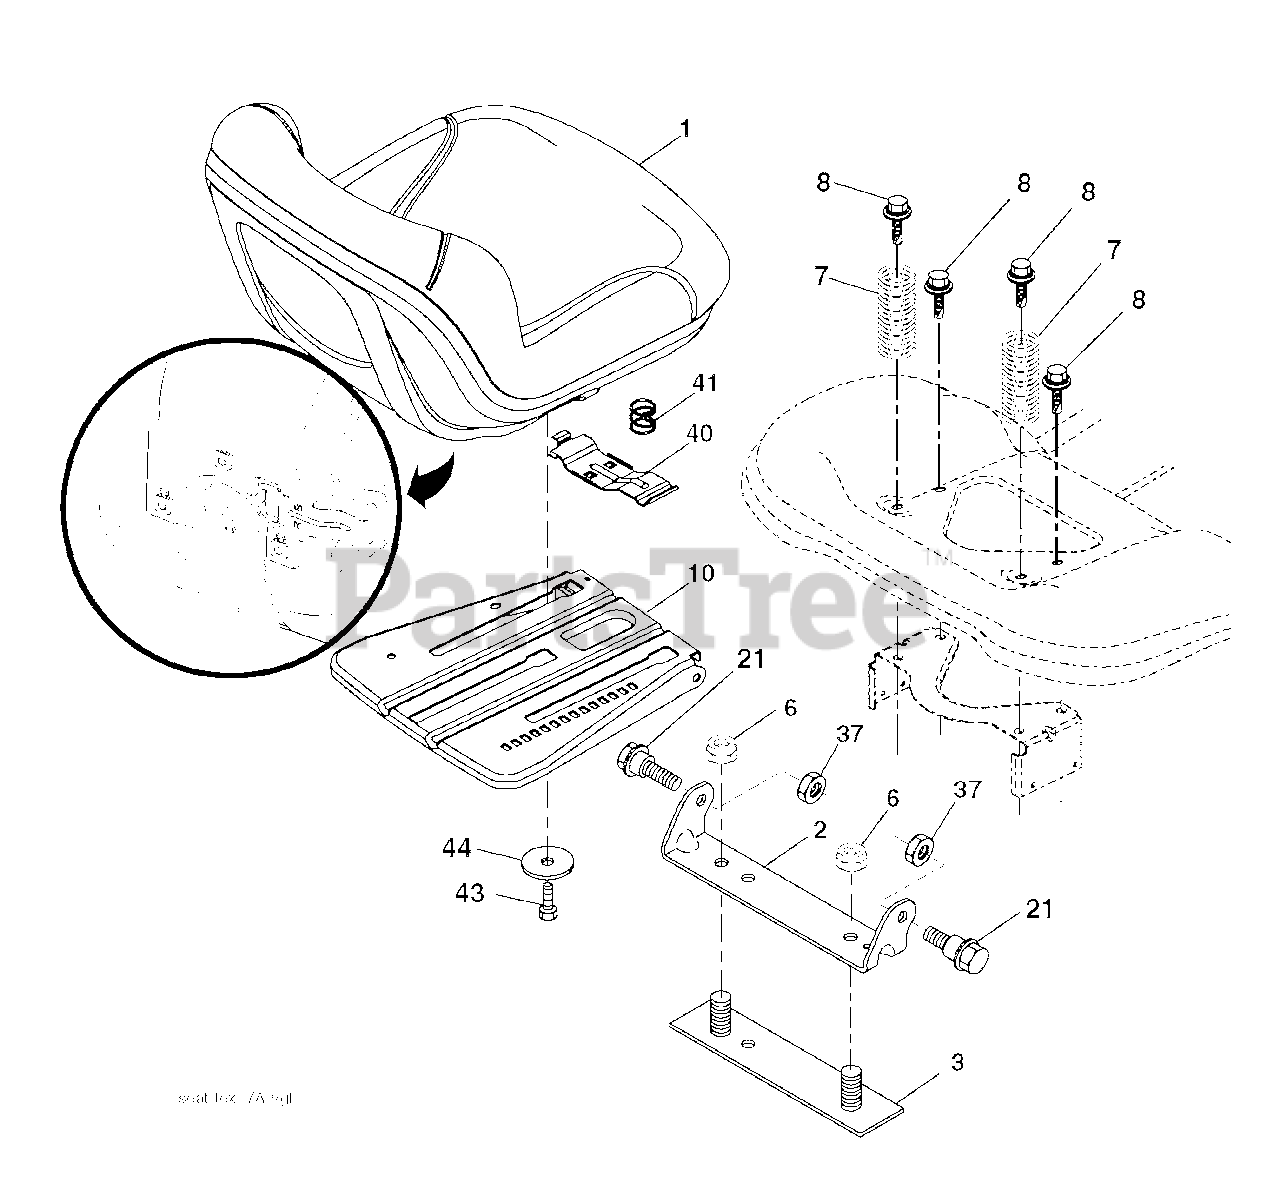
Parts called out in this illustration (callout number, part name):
1	SEAT.TG110.BLK.NO/LOGO.MILSC
2	BRKT.PIVOT.FENDER
6	NUT
7	SPRING COMPRESSION
8	BOLT, 5/16-18 X 1 3/4
10	PAN.ASM.SEAT.3PT
21	BOLT.SHOULDER.5/16-18
37	NUT.71038.31-18.HEX.NYLOCK
40	HANDLE.SLIDE.SEAT.TEX.BLACK
41	SPRING.LATCH.SEAT.TEX
44	WASHER 13/32 X 2-3/8 X 12GA
